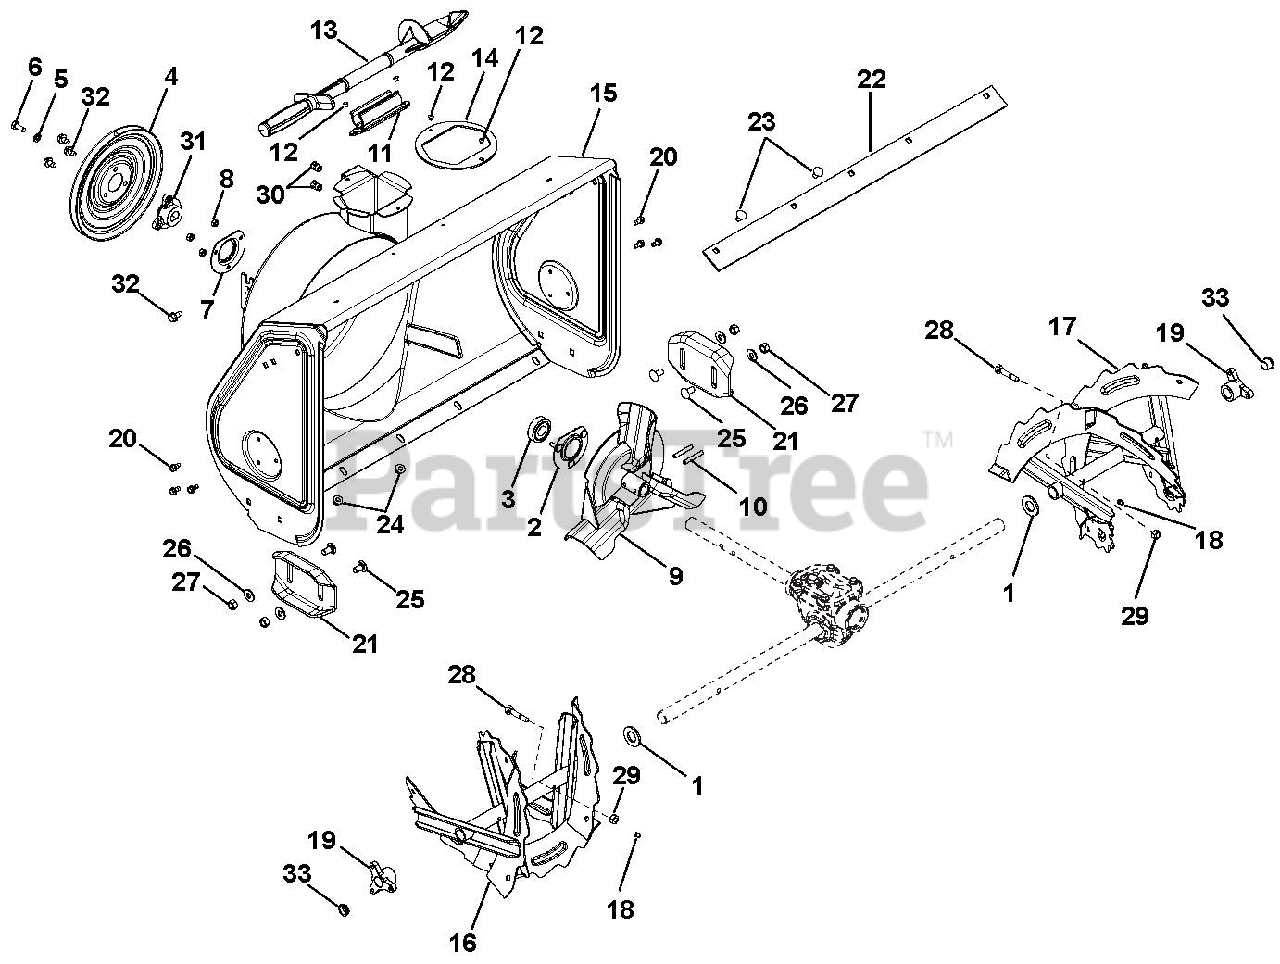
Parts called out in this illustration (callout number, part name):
1	@WSHR-FL-STL.812X1.50X.135YWZC
1	BSHG-SLV .75X1.12X1.062 NYL BK
2	BEARING FLANGE
3	BRG-BALL .750X1.750X.50
4	PULLEY,SPIN FORM SINGLE GROOVE
5	WSHR-LK .312X.097 HVY YWZC
6	BLT-HEX .31-24X.75 YWZC GR5
7	BEARING FLANGE
8	@NUT-LK-CTR .25-20 YWZC
9	IMPELLER, COMPACT 12" 3-BLADE
10	PIN-ROLL .250X1.75
11	MOUNT, SNOW CLEAN OUT
12	RVT-POP .187 YZ
13	DEVICE, SNOW CLEAN OUT
14	BAFFLE, COMPACT DISCHARGE
15	BLOWER HOUSING, 20"
15	BLOWER HOUSING, 22" HI ORANGE
15	BLOWER HOUSING, 24" HI ORANGE
16	AUGER, 20" RH, BLK SERR W/ZERK
16	RAKE, 24" RH, BLK SERR W/ZERK
17	AUGER, LH 20", BLK SERR W/ZERK
17	RAKE, 24" LH, BLK SERR W/ZERK
18	ZERK,FITTING .25X.125 DRIVE IN
19	BUSHING, RAKE SHAFT .75"
20	SCR-TAP .25-20X.50 HWH TR YWZ
21	SKID SHOE, REVERSIBLE - ORANGE
22	BLADE, SCRAPER - 20" COMPACT
22	SCRAPER BLADE, 22" COMPACT
22	SCRAPER BLADE, 24" COMPACT HI
23	BOLT, MODIFIED HEAD CARRIAGE
24	@NUT-LK-TOP-FLG .31-18 YWZC
25	@BLT-RHDSSQNK .38-16X.75 G5YZ
26	@WSHR-FL-STL.38X.875X.083 YWZC
27	@NUT-LK-CTR .38-16 YWZC
28	SHEAR BOLT WITH NUT
29	@NUT-LK-CTR .25-20 YWZC
30	NUT, THREADED INSERT .38-16
31	PULLEY HUB, BOLT-ON D-BORE .75
32	@SCR-TAP .31-18X.50 HWH TR YWZ
33	BSHG-FLG SPLIT NYLINER .75"ID
